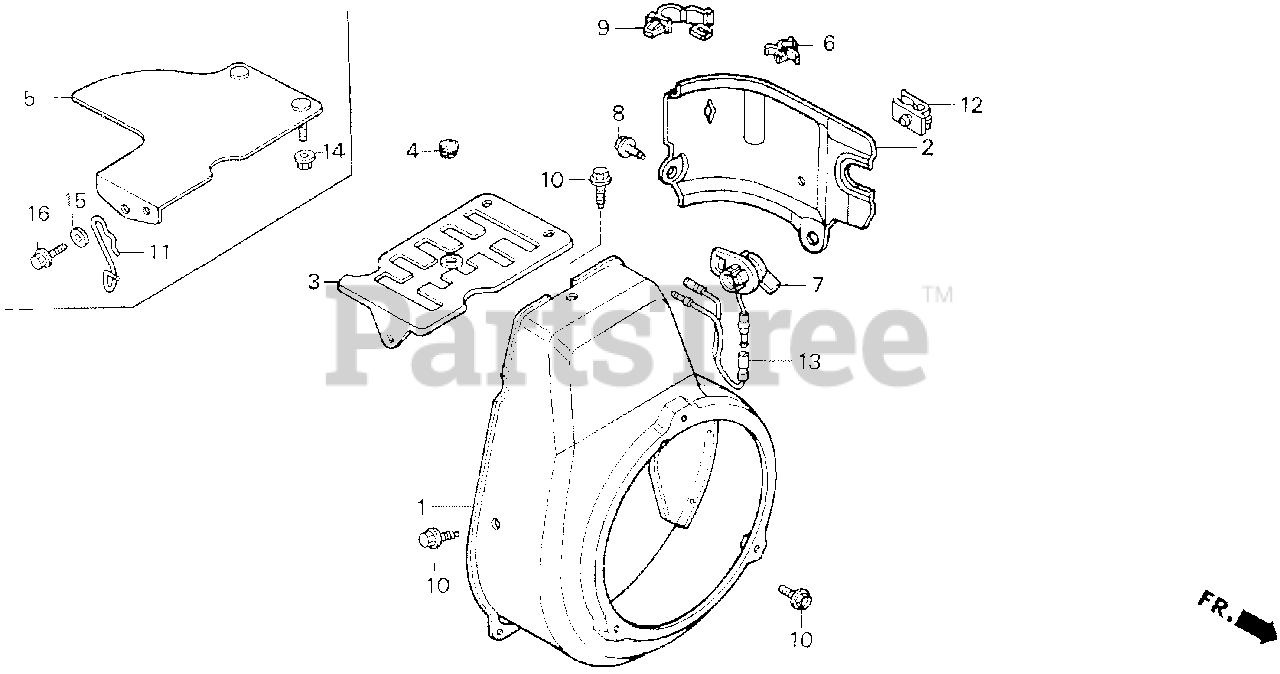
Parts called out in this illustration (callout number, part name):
1	COVER, FAN *R8* (BRIGHT RED)
1	COVER, FAN *T73* (EXEN GRAY)
2	SHROUD
5	COVER, TOP
7	SWITCH ASSY., ENGINE STOP
8	BOLT, FLANGE (6X12) (CT200)
9	CLIP, TUBE (7MM)
10	BOLT, FLANGE (6X12) (CT200)
11	GUIDE, WIRE
12	CLAMP, CORD
13	SUB-HARNESS
14	NUT, FLANGE (6MM)
15	WASHER, PLAIN (6MM)
16	BOLT, FLANGE (6X16)
